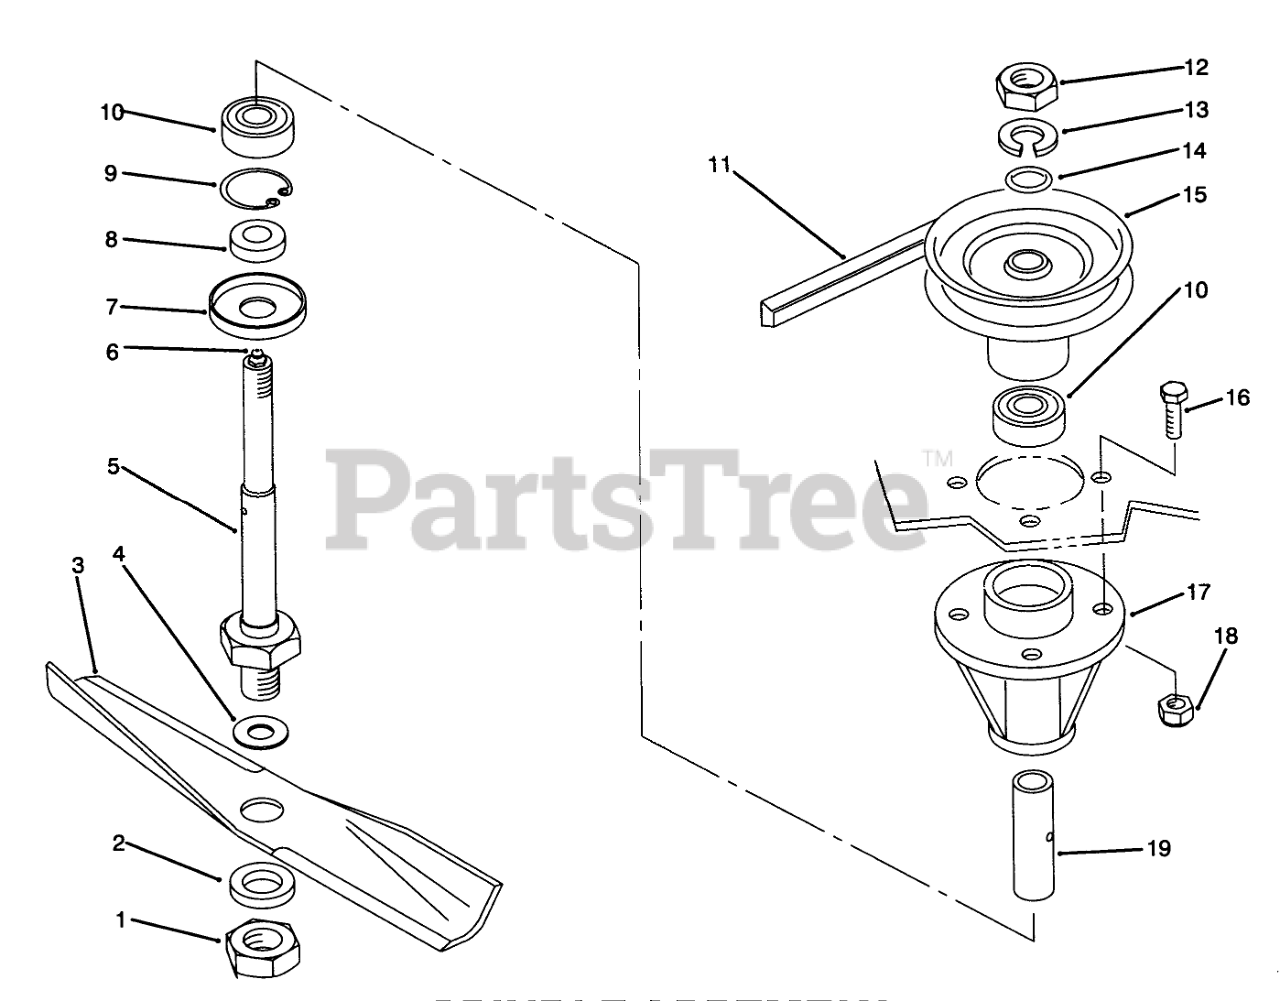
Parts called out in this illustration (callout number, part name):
1	NUT-JAM
2	WASHER-FLAT
3	14IN BLADE KIT
4	WASHER-FLAT
5	SHAFT-SPINDLE
6	FITTING-GREASE
7	BLADE-14IN
8	SPACER-BLADE
9	RING-RETAINING
10	BEARING-BALL
11	Belt
12	NUT-JAM
13	WASHER-LOCK
14	O RING
15	Pulley-Spindle
16	Bolt
17	HOUSING-SPINDLE
18	NUT-LOCK, NI
